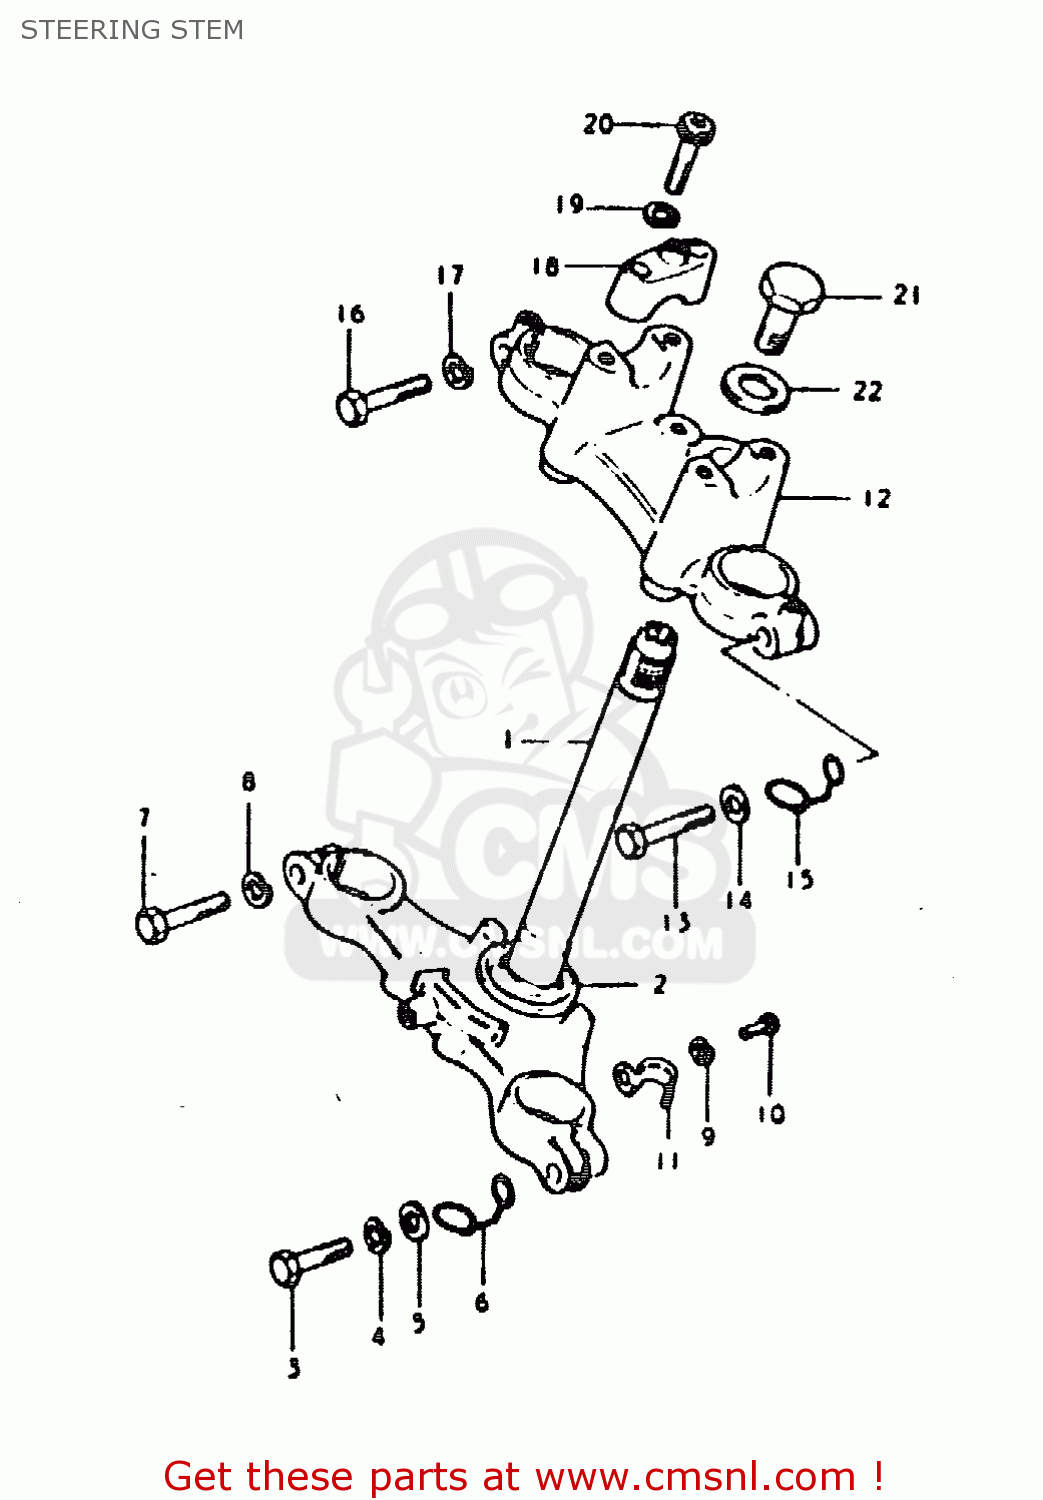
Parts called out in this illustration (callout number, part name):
1	STEERING STEM
2	RACE,STEERING OUTER LWR
3	BOLT
4	WASHER,LOCK 12
5	WASHER
6	CLIP
7	BOLT
8	WASHER,LOCK 12
9	LOCK WASHER
10	SCREW
11	CLIP,BRAKE CABLE
12	HEAD, STEERING STEM
13	BOLT 10X40
14	WASHER
15	CLIP
16	BOLT 10X40
17	LOCK WASHER
18	CLAMP,HANDLE HOLDER UPR
19	LOCK WASHER
20	BOLT 8X35
21	BOLT,FORK INNER TUBE
22	WASHER,STEM HEAD(10.5X30X3.2)
